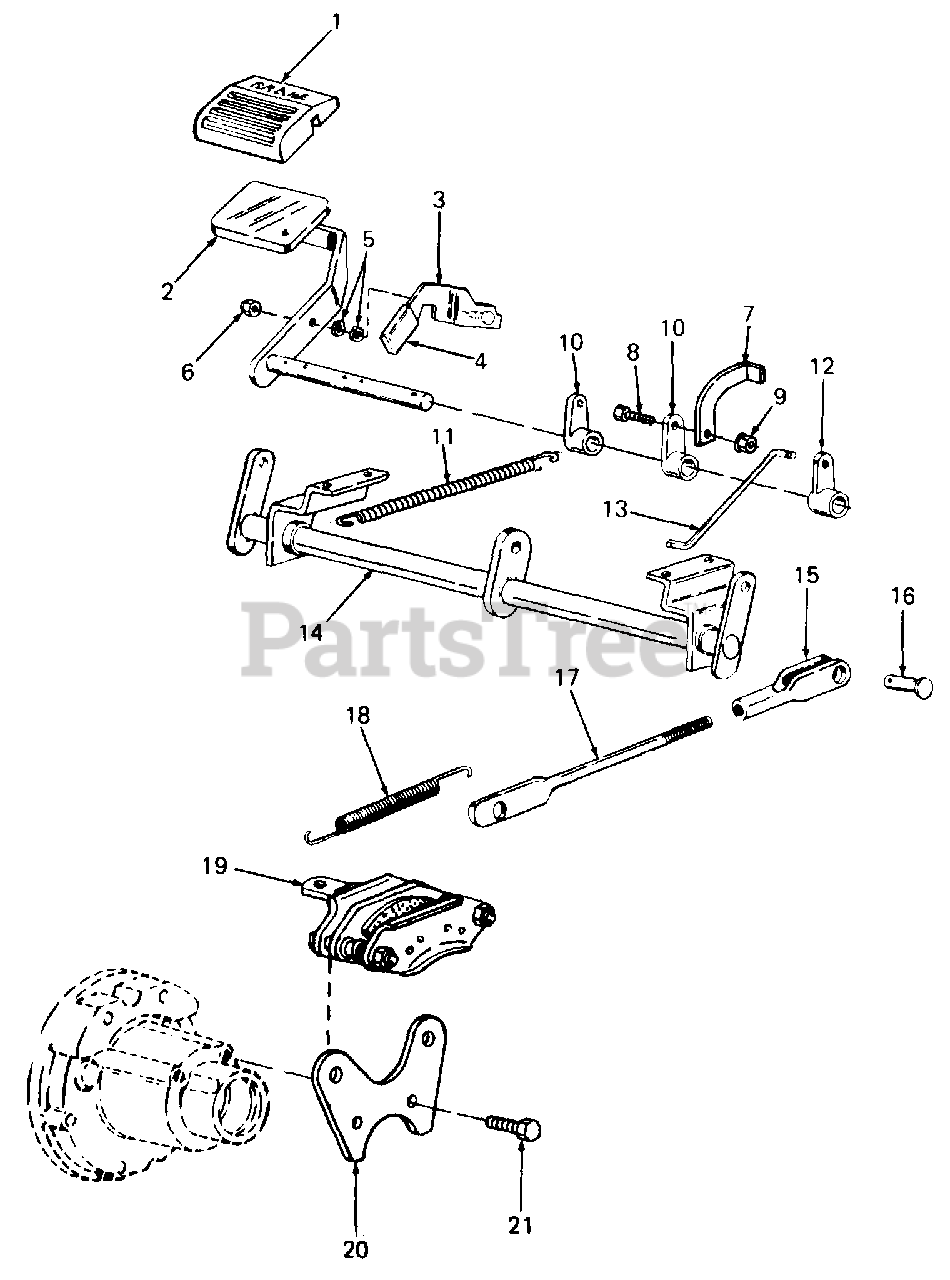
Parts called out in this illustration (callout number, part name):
1	Pad, Brake Pedal
2	Pedal Assy, Brake
5	Washer, Wave, 1/4 Dia
6	Nut, Hex Insert Lock, 1/4-20
8	Screw, Hex Cap, 3/8-16 X .75 Lg GR5
9	Nut, Hex Center Lock, 1/4-20
11	Spring, Return
15	Clevis, Adjustment
16	Pin, Clevis, 3/8 Dia X 1.0 Lg
17	Rod, Brake
18	Spring, Tension
19	Kit, Brake Caliper
20	Bracket, Brake Mounting
21	Screw, Hex Cap, 5/16-18 X 1.0 Lg GR5
